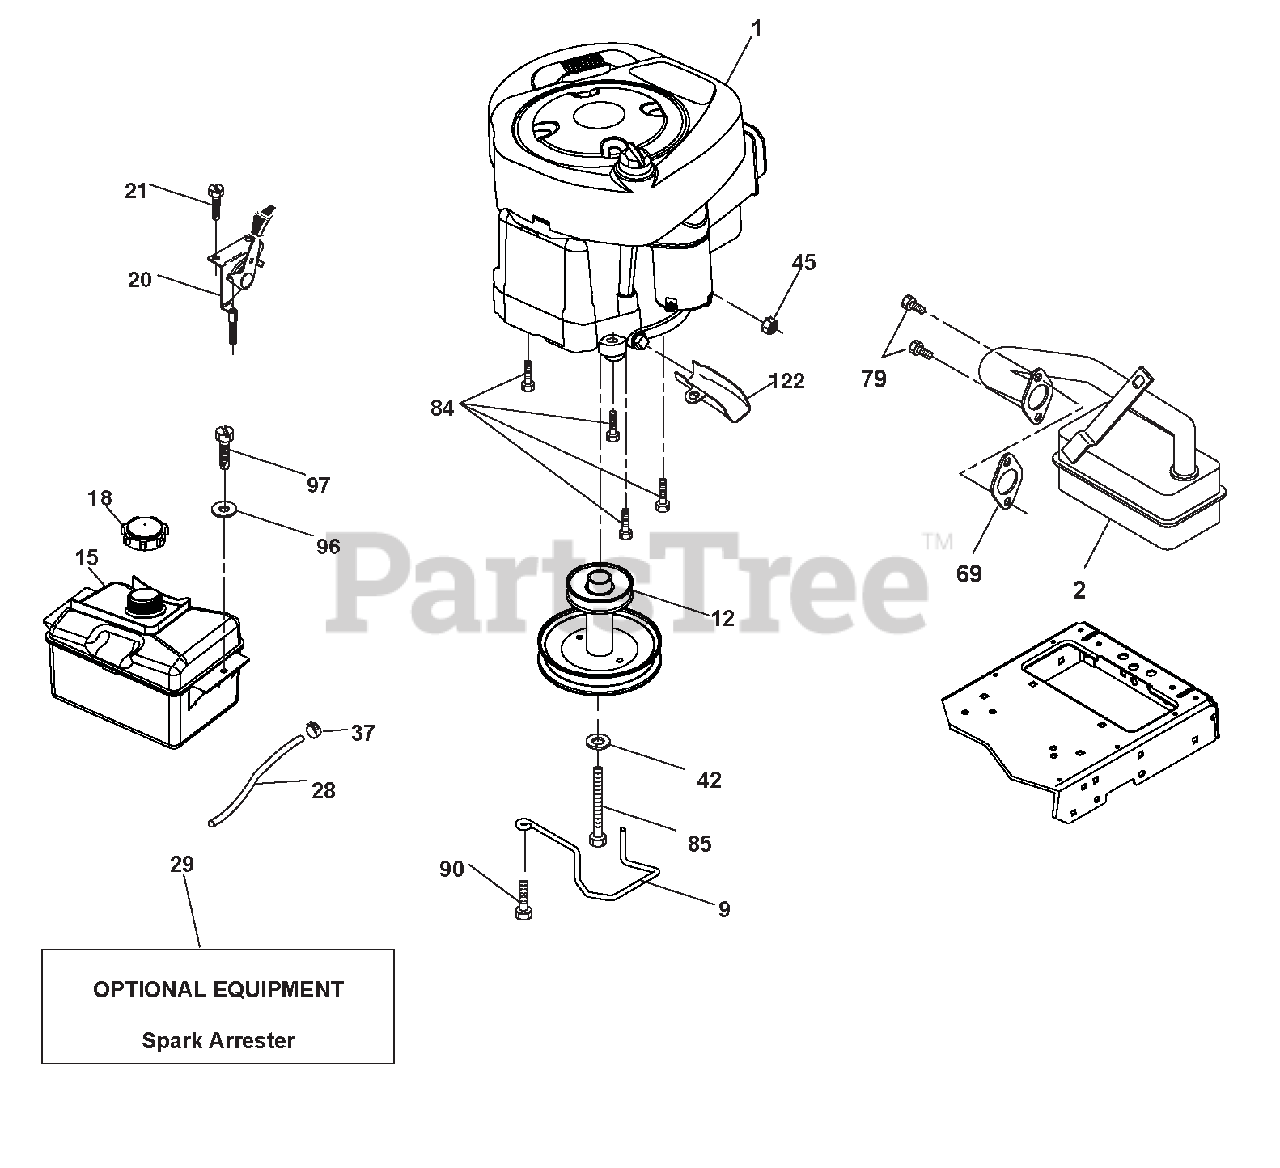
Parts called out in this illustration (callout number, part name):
1	ENGINE B&S MODEL NO. 31A507-1516-B1 (438749) (ORDER PARTS FROM ENGINE MANUFACTURER.)
2	Muffler Exhaust B&S
9	KEEPER BELT ENGINE
12	PULLEY.ENGINE
15	TANK FUEL
18	CAP.FUEL
20	CONTROL.THROTTLE
28	LINE.FUEL.22"FRONT.EMIS.CA.LP
29	KIT.SPARK ARRESTOR(392390 B&S)
37	CLAMP.HOSE.BLK.
42	WASHER.LOCK.HVY HLCL.SPR.7/16
45	Nut, Keps Hex 1/4-20 unc
69	Gasket Eng 1 313 Id Tin Plated
79	SCREW SOCKET HEAD 5/16-18 X 1
84	Screw 3/8-16 x <
85	BOLT.HEX.7/16-20X4XGR5-1.5THR.
90	SCREW.3/8-16X1.SMGML.TAP/R.BLK
96	WASHER.9/32 X 7/8 X 16GA.
97	SCREW.HEXWSH.THDROL.1/4-20X3/4
122	Extension Drain Oil
